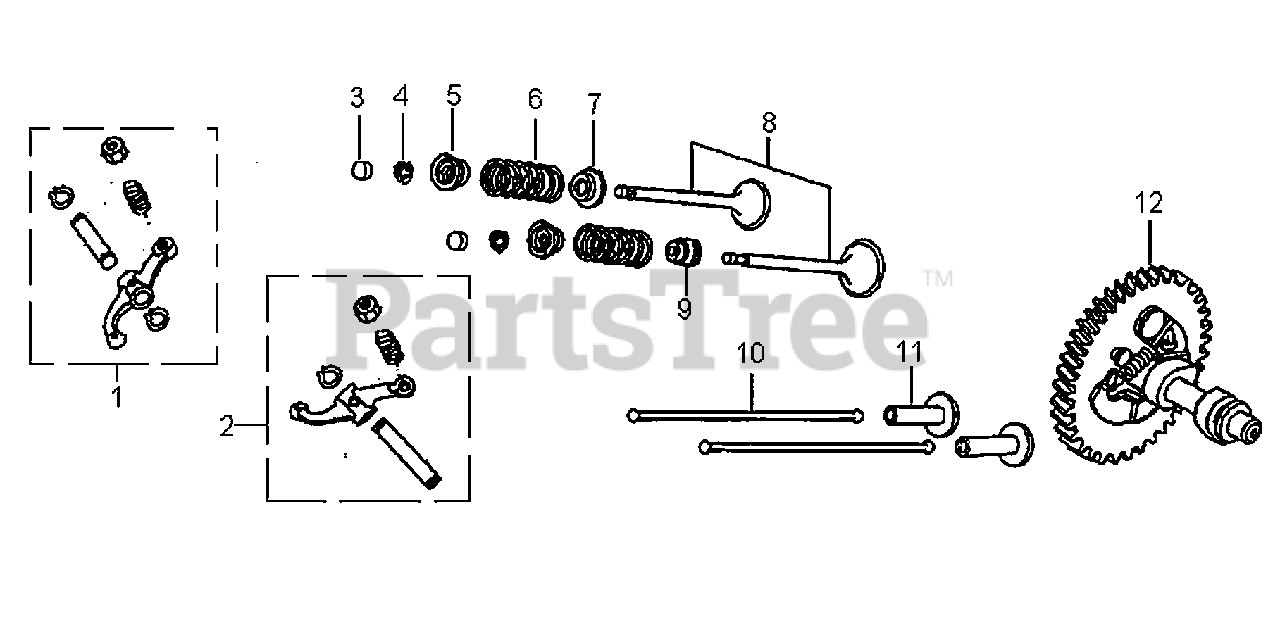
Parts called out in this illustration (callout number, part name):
1	ROCKER ARM ASSY.
2	ROCKER ARM ASSY.
3	ROTATOR,VALVE
4	VALVE LOCKER
5	RETAINER,VALVE SPRING
6	SPRING,VALVE
